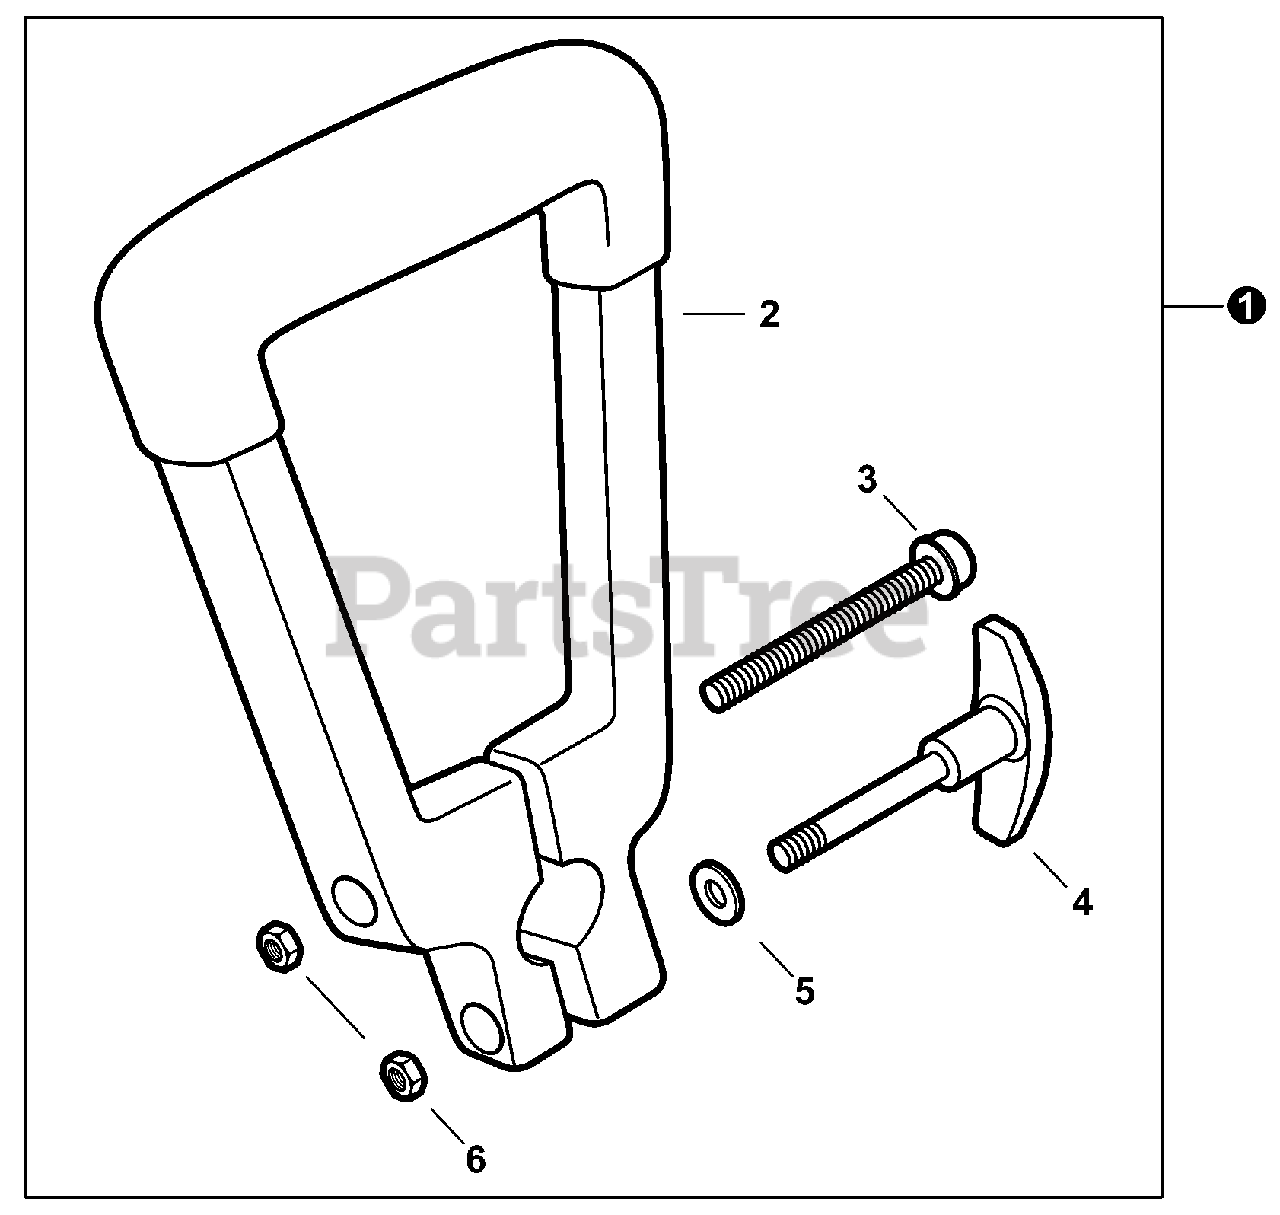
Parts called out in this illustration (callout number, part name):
1	HANDLE ASSY - SUPPORT
3	SCREW 6
4	KNOB, SCREW
5	WASHER 6
6	NUT, HEX M6
